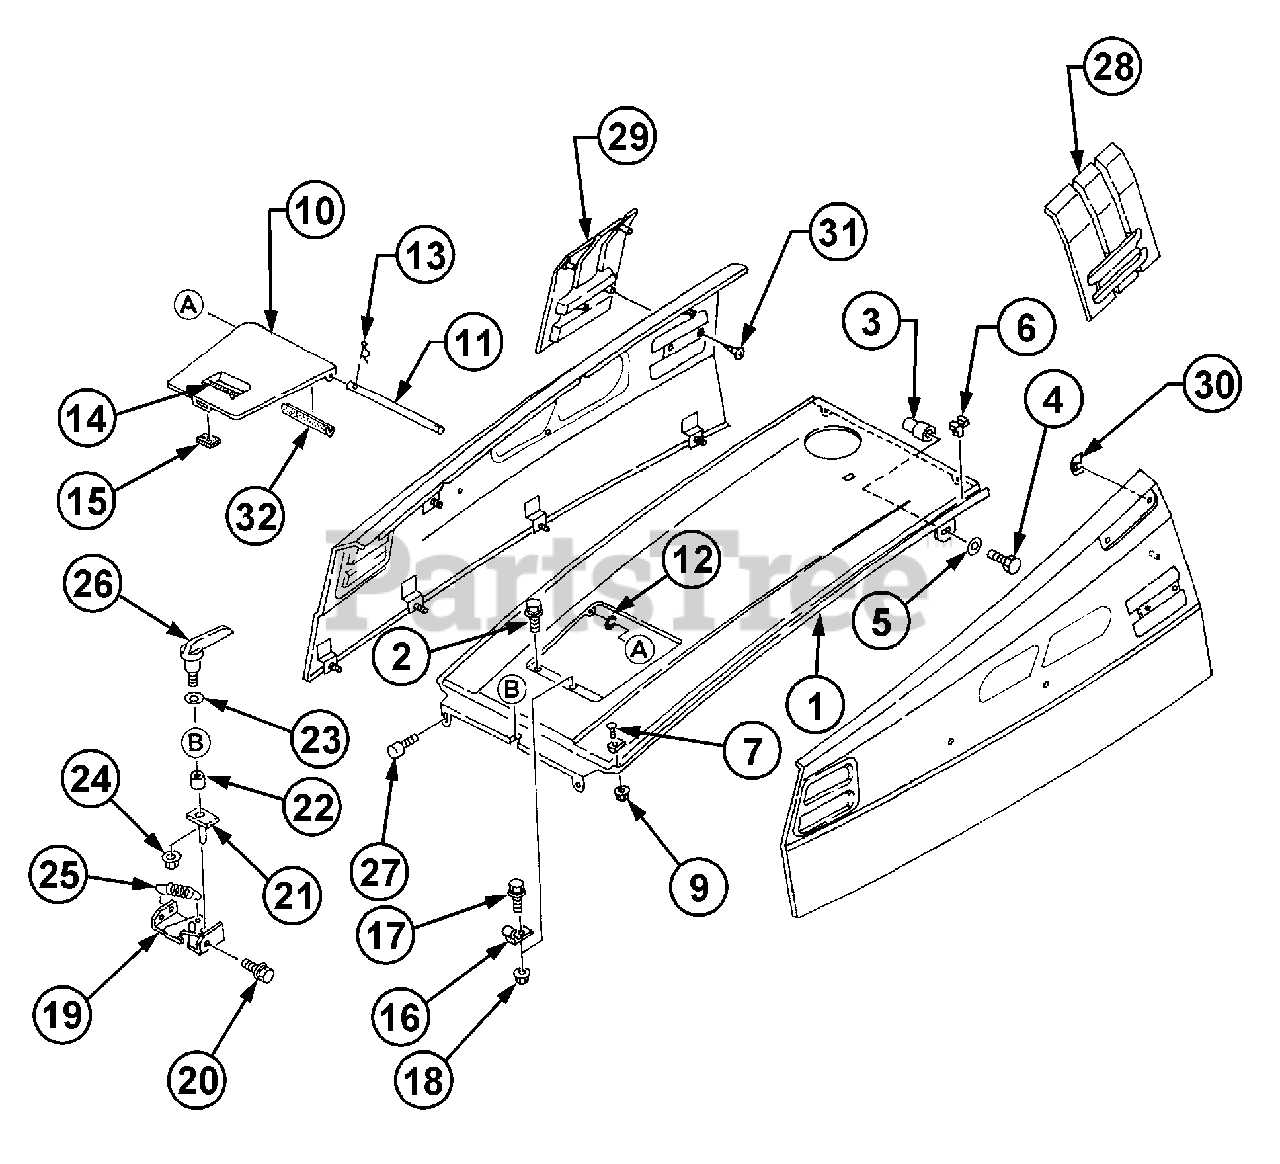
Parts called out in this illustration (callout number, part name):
15	Plate, Rubber
19	Bracket, Lever
20	Bolt, w/Washer
31	Screw, Tapping
